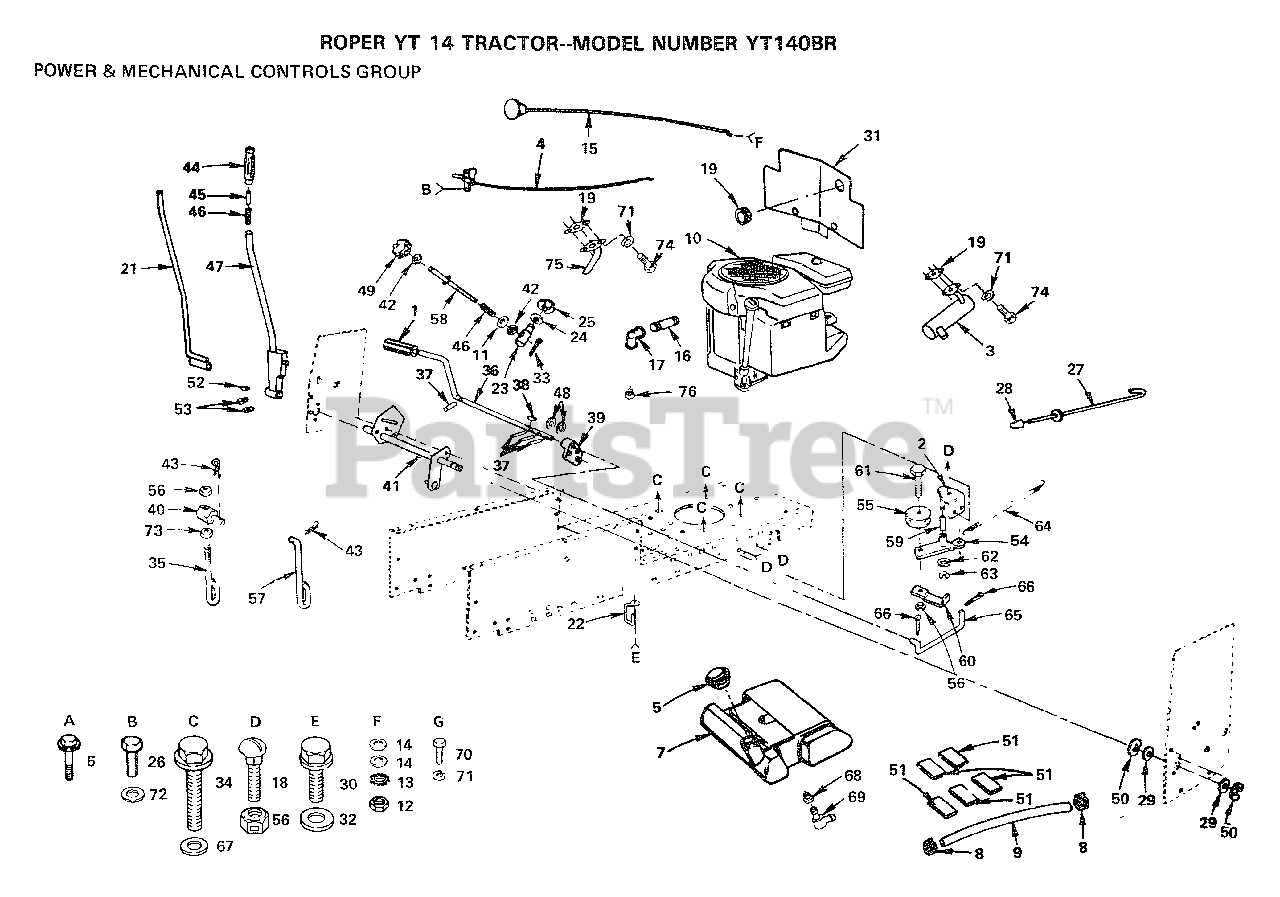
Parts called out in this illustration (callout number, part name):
1	PEDAL COVER T
4	THROTTLE CONTROL
11	WASHER
13	LOCKWASHER
14	WASHER
16	PIPE NIPPLE LT
17	ELBOW
18	BOLT
21	ROD ASSY-LEVER LT
24	WASHER
25	KLIP RING
26	SCREW
28	PLUNGER CAP T
29	WASHER
30	SCREW
32	WASHER
34	SCREW LT
35	LINK LIFT LT
36	FOOT SHAFT PEDAL
39	ARM BRAKE LT
42	NUT
44	GRIP
46	SPRING T
47	LEVER ASSY LT
50	RING
51	PAD-SPACER T
57	LIFT LINK LT
58	ROD ADJUST LT
59	"LY, BEARING"
62	WASHER T
63	KLIP RING
64	"SPRING, RETURN LT"
65	"LINK, CLUTCH T"
66	COTTER PIN
67	WASHER
68	BUSHING OUTLET T
69	FUEL TANK STEM GT
70	BOLT
71	LOCKWASHER
72	WASHER
73	NUT.HEX.3/8-16UNC
75	EXHAUST TUBE T
76	PLUG OIL DRAIN
